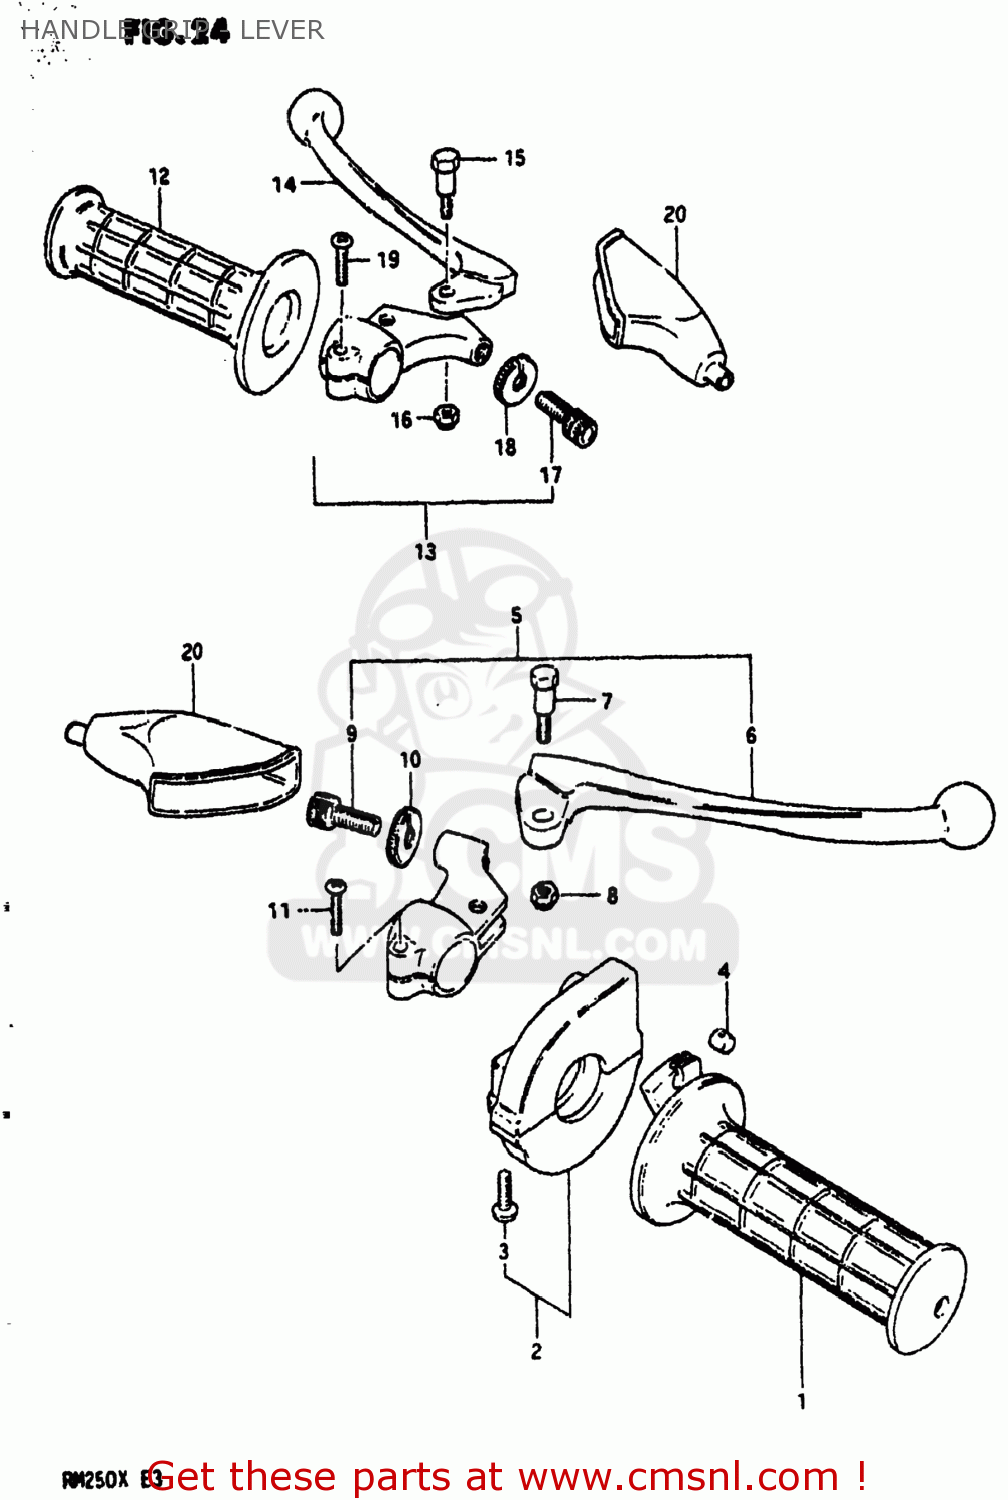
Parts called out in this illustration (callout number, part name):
1	GRIP,THROTTLE
2	CASE ASSEMBLY,THROTTLE
3	SCREW
4	PIECE,THROTTLE END
5	LEVER ASSEMBLY,BRAKE
6	LEVER,BRAKE
7	BOLT,LEVER
8	NUT 6MM
9	ADJUSTER,CABLE
10	NUT,CABLE ADJUSTER
11	SCREW
12	GRIP,LEFT
13	LEVER ASSEMBLY,CLUTCH
14	LEVER,CLUTCH
15	BOLT,LEVER
16	NUT 6MM
17	ADJUSTER,CABLE
18	NUT,CABLE ADJUSTER
19	SCREW
20	COVER,CLUTCH LEVER
